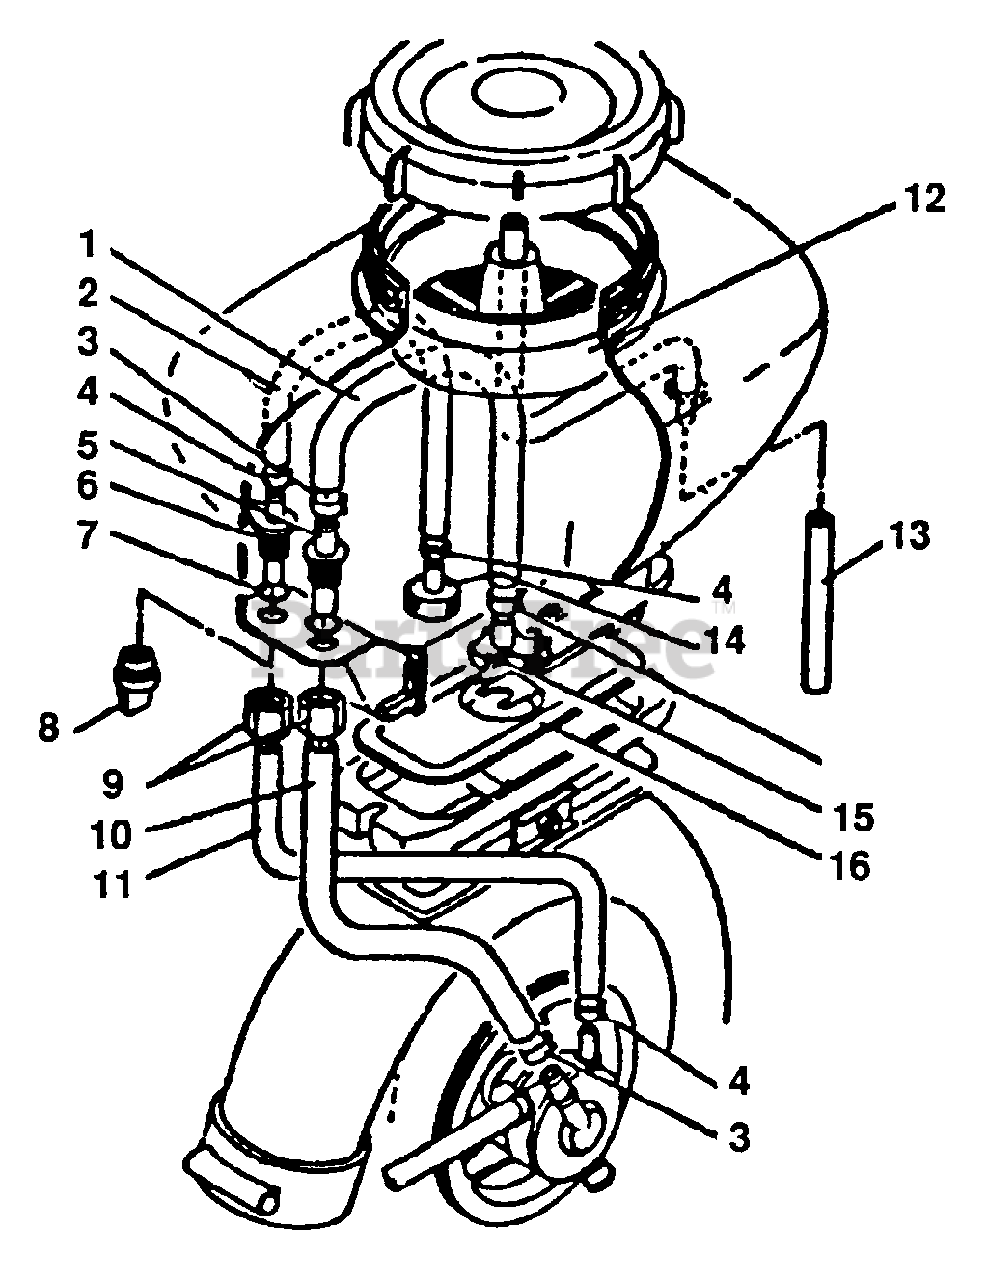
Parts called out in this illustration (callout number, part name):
1	PIPE
2	HOSE, FLUID
3	CLIP - 13
4	CLAMP
5	CONNECTOR, PIPE
6	NIPPLE
9	NUT, CONNECTOR
10	PIPE
11	HOSE, FLUID
12	FILTER, TANK
13	PIPE, VENT - OUTER
14	NIPPLE
15	MOUTH, SUCTION
16	Plate, Base
